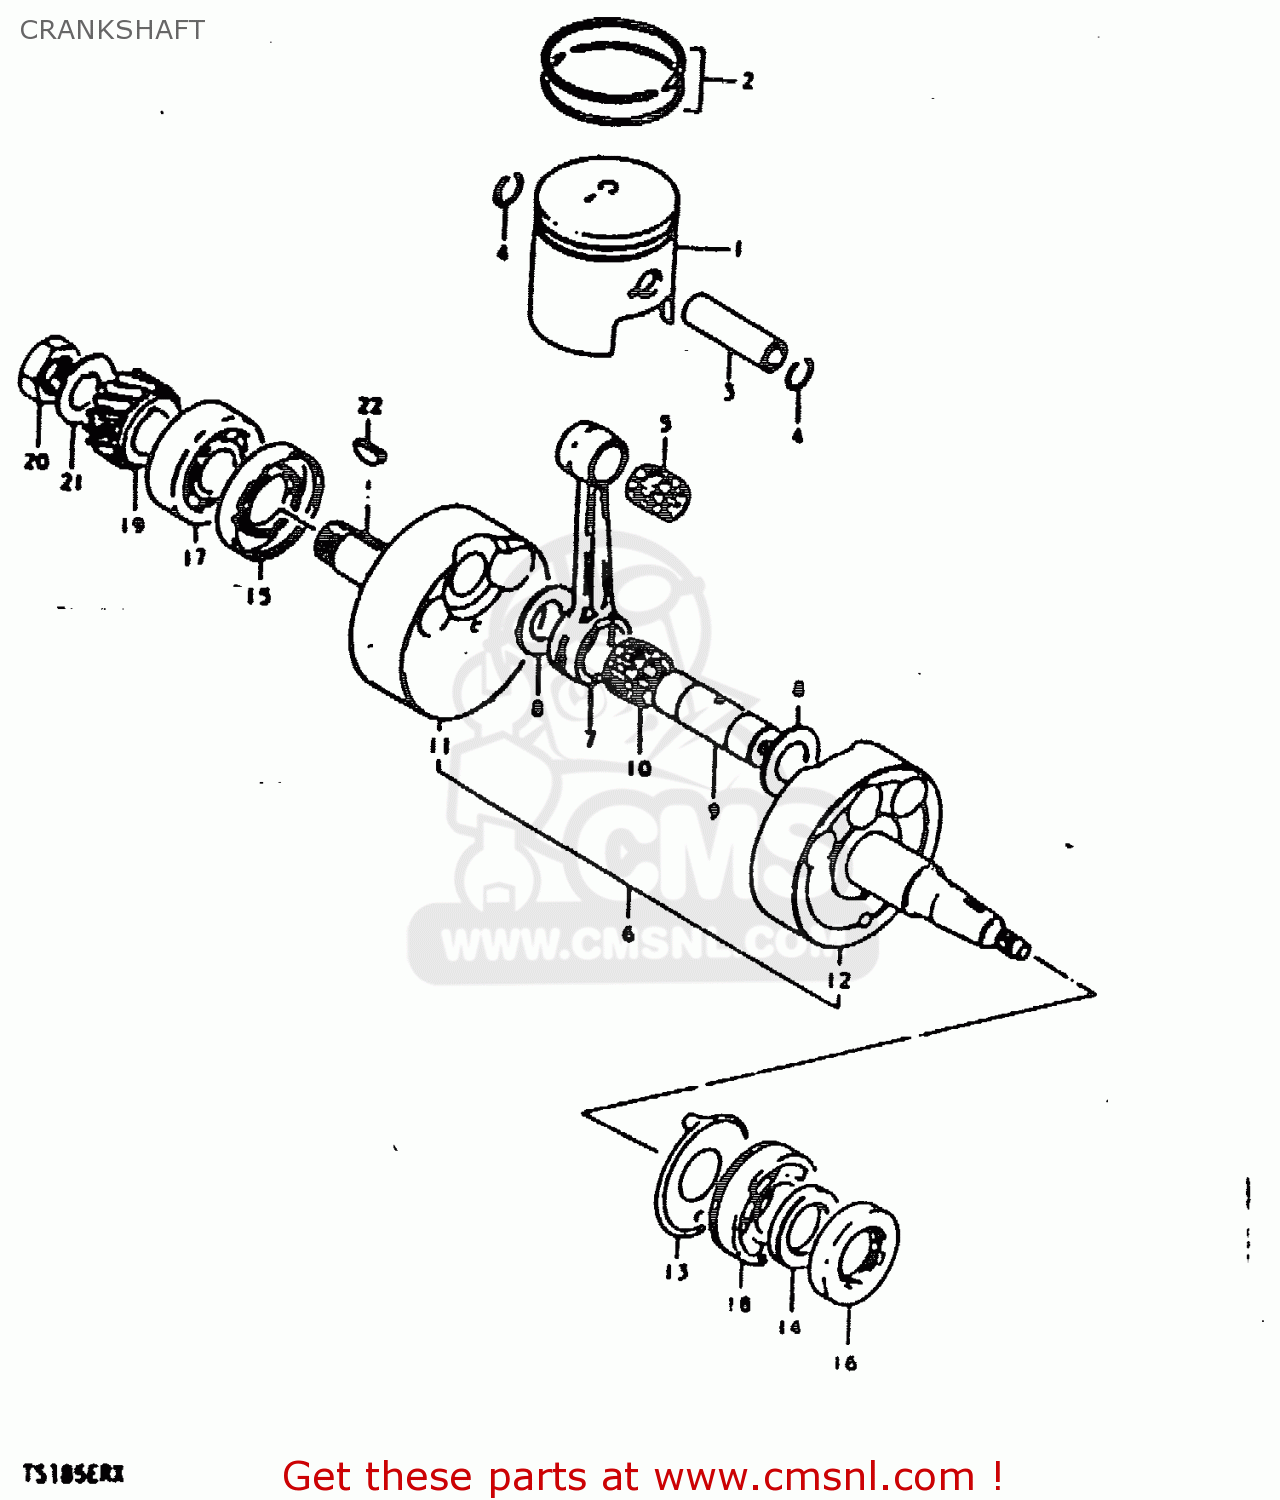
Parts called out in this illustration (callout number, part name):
1	PISTON
2	RING SET,PISTON
3	PIN,PISTON
4	RING,SNAP 16MM
5	BEARING
6	CRANKSHAFT ASSEMBLY
7	ROD, CONNECTING
8	WASHER(22X35X1)
9	PIN,CRANK
10	BEARING 22X28X16
11	CRANKSHAFT,R
12	CRANKSHAFT,LEFT
13	PLATE,CSHAFT OIL GUIDE
14	SPACER(25X34X4.5)
15	SEAL,OIL(26X52X8)
16	SEAL,OIL(25X44X7)
17	BEARING
18	BEARING(25X62X17)
19	GEAR,PRIMARY DRIVE
20	NUT
21	WASHER
22	KEY
